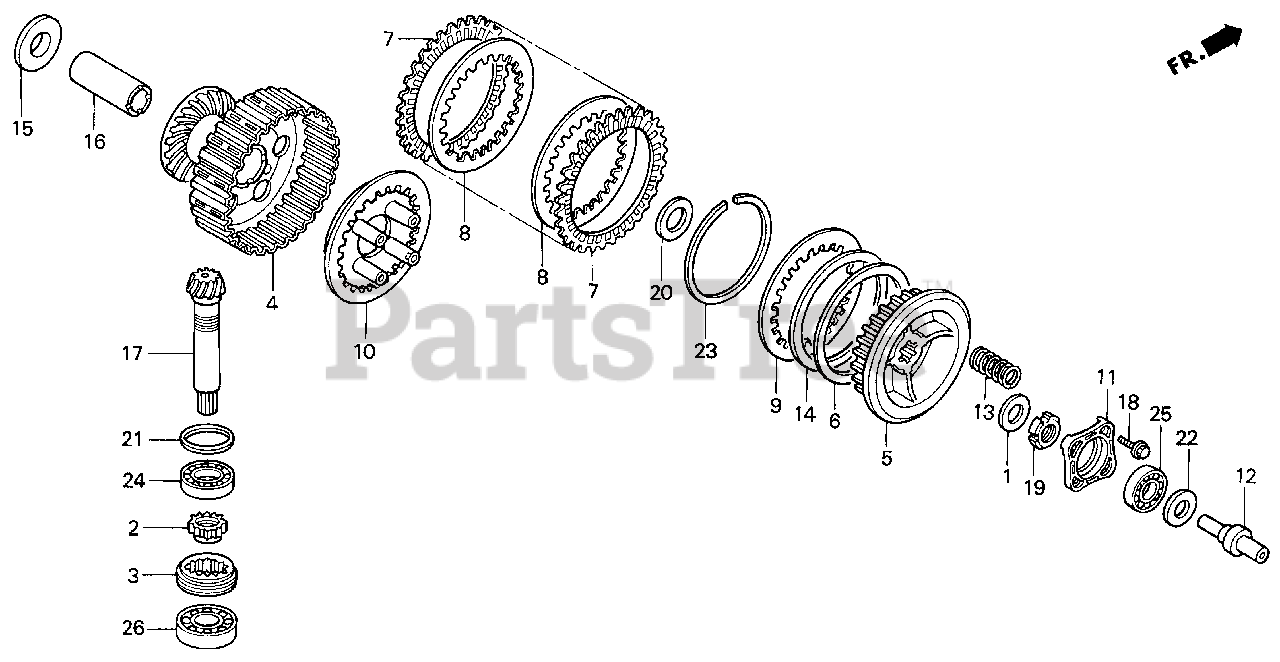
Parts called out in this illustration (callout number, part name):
1	WASHER, OIL FILTER ROTOR LOCKING
2	NUT, LOCK (22MM)
3	NUT, LOCK (48MM)
4	CLUTCH (OUTER)
5	CENTER, CLUTCH
6	SEAT, JUDDER SPRING
7	DISK, CLUTCH FRICTION
8	PLATE, CLUTCH
9	PLATE, CLUTCH
10	PLATE, CLUTCH PRESSURE
11	PLATE, CLUTCH LIFTER
12	ROD, CLUTCH LIFTER
13	SPRING, CLUTCH
14	SPRING, CONED DISK
15	SHIM A, MAINSHAFT (8.25MM)
15	SHIM B, MAINSHAFT (8.30MM)
15	SHIM C, MAINSHAFT (8.35MM)
15	SHIM D, MAINSHAFT (8.40MM)
15	SHIM E, MAINSHAFT (8.45MM)
15	SHIM F, MAINSHAFT (8.50MM)
15	SHIM G, MAINSHAFT (8.55MM)
15	SHIM H, MAINSHAFT (8.60MM)
15	SHIM I, MAINSHAFT (8.65MM)
15	SHIM J, MAINSHAFT (8.70MM)
15	SHIM K, MAINSHAFT (8.75MM)
16	COLLAR, MAINSHAFT
17	SHAFT, INPUT
18	BOLT, SPECIAL FLANGE (6X28)
19	NUT, LOCK (16MM)
20	WASHER (20X37X2)
21	SHIM A, PINION GEAR (36X43.5X1.25)
21	SHIM B, PINION GEAR (36X43.5X1.30)
21	SHIM C, PINION GEAR (36X43.5X1.35)
21	SHIM D, PINION GEAR (36X43.5X1.40)
21	SHIM E, PINION GEAR (36X43.5X1.45)
21	SHIM F, PINION GEAR (36X43.5X1.50)
21	SHIM G, PINION GEAR (36X43.5X1.55)
21	SHIM H, PINION GEAR (36X43.5X1.60)
21	SHIM I, PINION GEAR (36X43.5X1.65)
21	SHIM J, PINION GEAR (36X43.5X1.70)
21	SHIM K, PINION GEAR (36X43.5X1.75)
22	SHIM A, CLUTCH LIFTER (1.0MM)
22	SHIM B, CLUTCH LIFTER (1.2MM)
22	SHIM C, CLUTCH LIFTER (1.4MM)
22	SHIM D, CLUTCH LIFTER (1.6MM)
22	SHIM E, CLUTCH LIFTER (1.8MM)
22	SHIM F, CLUTCH LIFTER (2.0MM)
22	SHIM G, CLUTCH LIFTER (2.2MM)
22	SHIM H, CLUTCH LIFTER (2.4MM)
22	SHIM I, CLUTCH LIFTER (2.6MM)
22	SHIM J, CLUTCH LIFTER (2.8MM)
22	SHIM K, CLUTCH LIFTER (3.0MM)
23	SET-RING, SPECIAL (82.5MM) (NOT AVAILABLE)
24	BEARING, RADIAL BALL (60/22)
24	BEARING, RADIAL BALL (60/22) (TMB)
25	BEARING, RADIAL BALL (16003)
26	BEARING, RADIAL BALL (6204)
